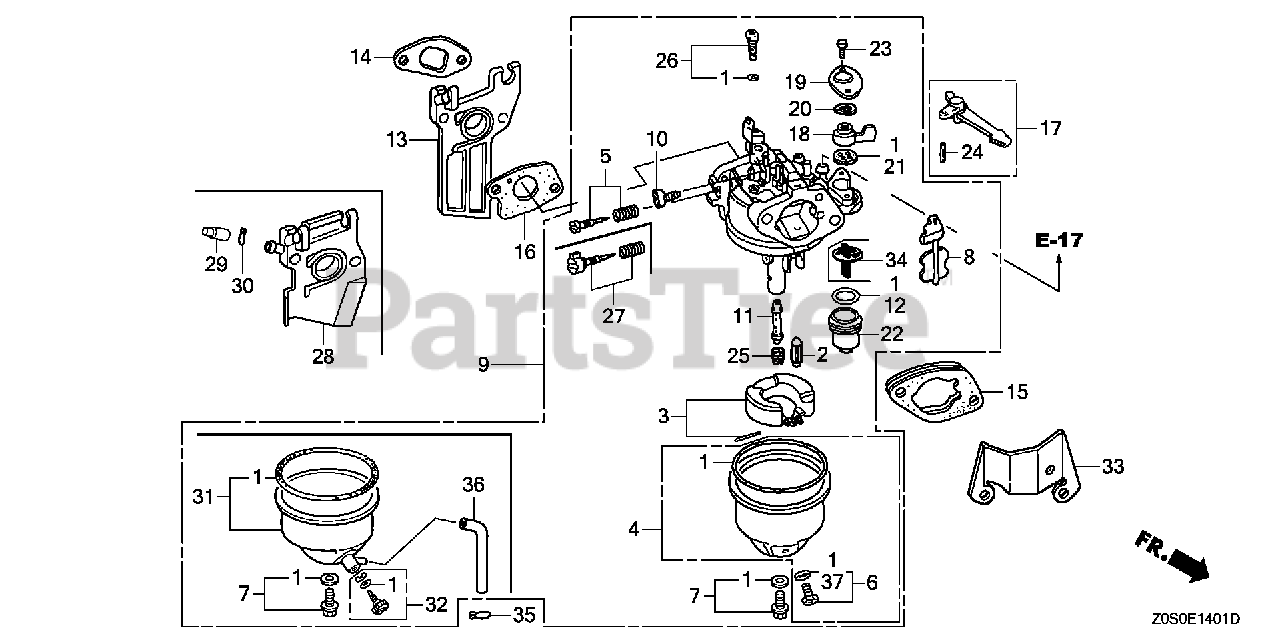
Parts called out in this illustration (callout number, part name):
1	GASKET SET
2	VALVE SET, FLOAT (SEAT NOT INCLUDED)
4	CHAMBER SET, FLOAT
6	SCREW SET, DRAIN
7	SCREW SET
9	CARBURETOR ASSY. (BE60Q A)
10	SCREW, THROTTLE STOP
11	NOZZLE, MAIN
12	GASKET, FUEL STRAINER CUP
13	INSULATOR, CARBURETOR
14	GASKET, INSULATOR
15	SPACER, CARBURETOR
16	GASKET, CARBURETOR
17	LEVER, CHOKE (STD)
18	LEVER, PETCOCK
19	PLATE, LEVER SETTING
20	SPRING, PETCOCK LEVER
21	GASKET, PETCOCK
22	CUP, FUEL STRAINER
23	SCREW, PAN (3X6)
24	PIN, SPRING (2X12)
25	JET, MAIN (#58)
25	JET, MAIN (#60)
25	JET, MAIN (#62)
26	JET SET, PILOT (#35)
27	SCREW SET, PILOT (CARBURETOR NO.)
